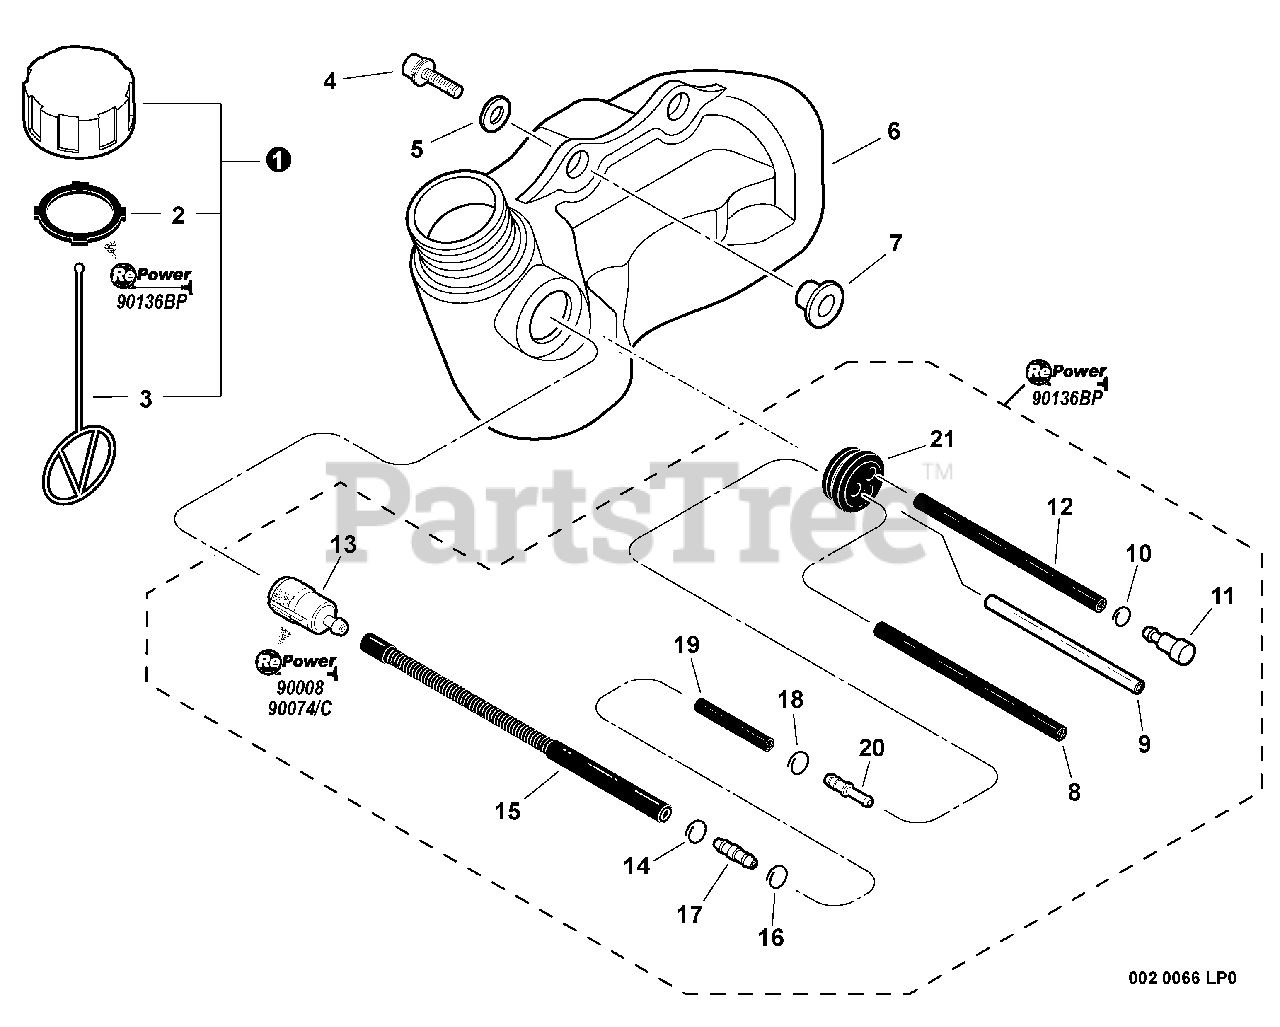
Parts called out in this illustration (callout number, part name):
1	CAP ASSY, FUEL
2	GASKET, FUEL CAP
3	CONNECTOR, CAP L= 123
4	BOLT 5×20
5	WASHER 5.5×12×0.8
6	TANK, FUEL
7	COLLAR 5
8	PIPE, FUEL 3×5×61 BLACK
9	PIPE, FUEL 3×6×75 CLEAR
10	CLIP Ø6
11	VENT ASSY
12	PIPE, FUEL 3×6×50 BLACK
13	FILTER, FUEL
14	CLIP 6.6 MM
15	PIPE, FUEL 3×7×100 FLEXIBLE
17	CONNECTOR, PIPE
19	PIPE, FUEL 3×6×35 BLACK
20	CONNECTOR, PIPE Ø5ר3.5
21	GROMMET, FUEL
22	FILTER KIT - REPOWER
23	TUNE-UP KIT - REPOWER
24	FUEL SYSTEM KIT
